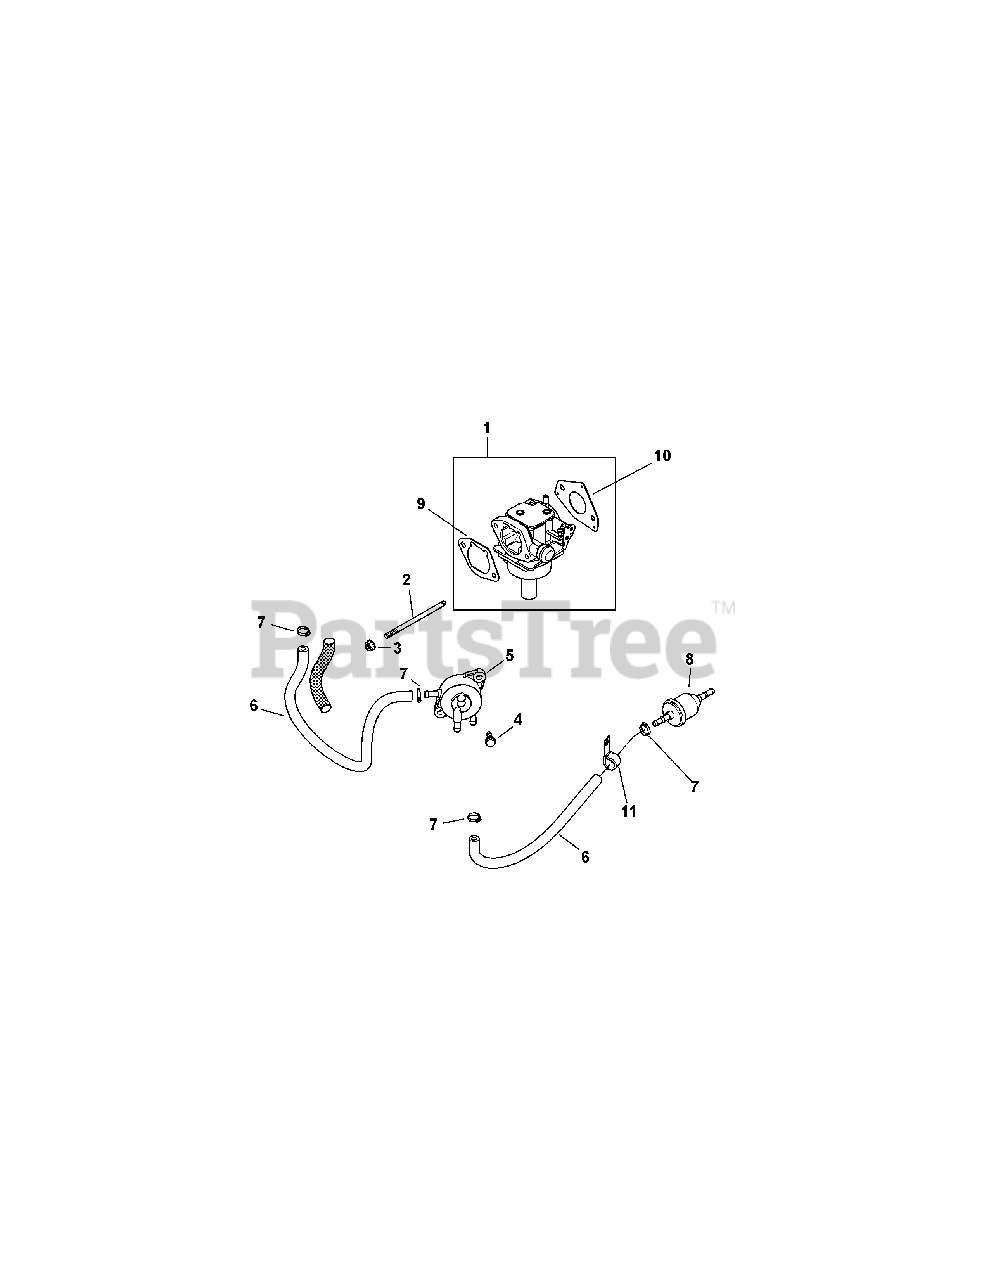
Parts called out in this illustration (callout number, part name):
1	Carburetor Kit
2	Stud, M6 x 1.0 x 106
3	Flange Nut, M6 x 1.0
4	Tap Screw, M6 x 1.7 x 18
6	Fuel Line
7	Hose Clamp, 1/2
9	Air Cleaner Base Gasket
10	Carburetor Gasket
